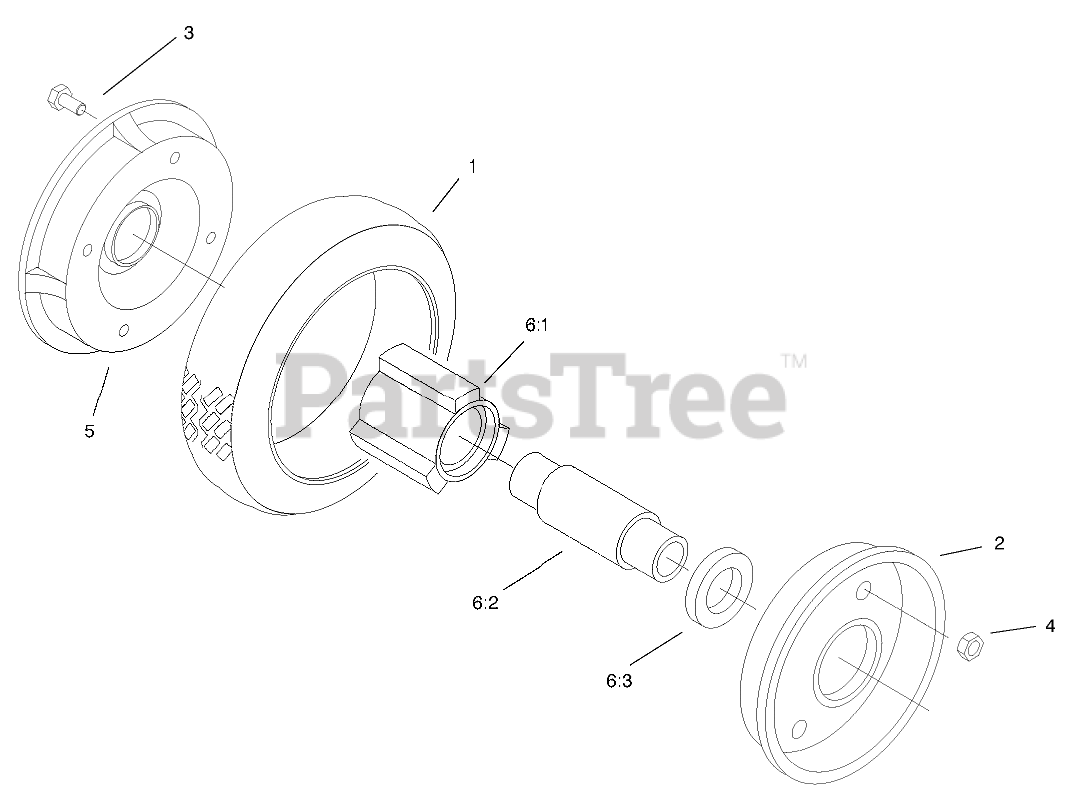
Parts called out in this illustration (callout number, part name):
2	PLATE-WHEEL, HALF
3	SCREW-HH
4	NUT-LOCK, NI
5	WHEEL HALF AND GEAR ASM
6	HUB and BEARING ASM
6:1	HUB-BEARING
6:2	SPACER-BEARING
6:3	BEARING-WHEEL
